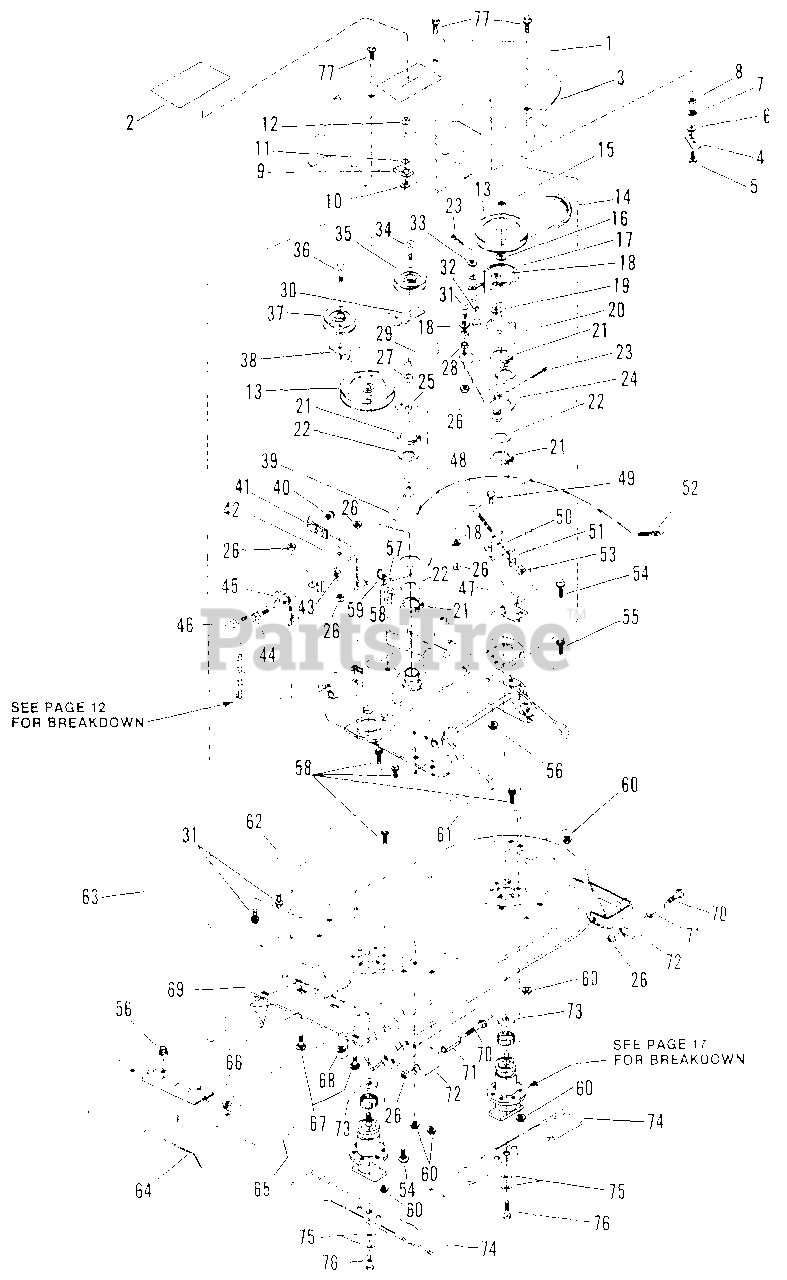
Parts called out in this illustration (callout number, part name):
1	ASSEMBLY, 41" Cover-Top
2	DECAL-CAUTION
3	ASSEMBLY, 41" Cover-Bottom
4	GUIDE, Belt
5	SCREW, 1/4-20 x 1/2" Hex Head Cap
6	WASHER, 1/4 Flat
7	WASHER, 1/4 Internal Tooth Lock
8	NUT, 1/4 Hex
9	CLIP
10	RETAINER, Bolt, 3/8"
11	WASHER, 3/8 Split Lock
12	NUT, 3/8-16 Hex
13	PULLEY, 5" O.D.
15	LOCKNUT, 3/4-16 Hex Jam
16	WASHER, 3/4 Flat
17	BAND, Brake Assembly
18	WASHER, 3/8" Flat
19	SPACER
20	BRAKE DRUM
21	RING, 2" External Retaining
22	WASHER, 2" I.D.
23	COTTER-PIN, 3/32 x 3/4"
24	BRAKE ARM ASSEMBLY
25	ANCHOR. Bl. Cont. Cable
26	LOCKNUT, 3/8-24 Hex
28	SPACER. 3/8 I.D.
30	RESTRICTOR, Belt
31	SCREW, 3/8-24 x 3/4" Hex Hd. Cap
32	PIN, 1/4 Clevis
33	WASHER, 1/4 Flat
34	SCREW, 3/8-24 x 2" Hex Hd. Cap
35	PULLEY, Idler
36	SCREW, 3/8-24 x 1-3/4" Hex Hd. Cap
37	PULLEY. Idler
38	GUIDE, Belt
39	IDLER ARM ASSM'Y.
40	SCREW. 5/16-18 x 5/8" HFST
41	BRACKET, Cable
42	SUPPORT, Idler
43	NUT, 3/8-16 Hex
44	SCREW, 3/8-16 x 1"
45	BRACKET
46	SCREW, 3/8-16 x 3/4" Hex Cap
47	BRACKET, Height Indicator
48	EYE-BOLT
49	BOLT, 5/16-18 x 3/4" SNC
50	ANCHOR
51	T-NUT
52	SPRING, Blade Brake
53	NUT, 1/4-20 Hex
54	BOLT, 3/8-16 x 3/4" SNC
55	BOLT, 3/8-16 x 3/4" HFL
56	NUT, 5/16-18 HFL
57	BRACKET, Deck Interlock
58	SCREW, 1/4-28 x 5/8" HHC
59	NUT, 1/4-28
60	NUT, 3/8-16 HFL
61	DECAL-CAUTION (Rotating Blades)
62	PLATE, Model Number
63	DECAL-CAUTION (Rotating Blades)
64	ASSEMBLY, Side Chute
65	DECAL, Danger (Keep Hands & Feet Away)
66	WINGNUT, 5/16-18
67	BOLT, 5/16-18 x 5/8" SNC
68	RETAINER, Bolt, 5/16
69	ASSEMBLY, Deck
70	SCREW, 3/8-24 x 3-3/4" HHC
71	SPACER
72	ROLLER
74	BLADE, 21"
75	WASHER, Cone
76	SCREW, 3/8-24 x 1-1/4"
77	SCREW, 1/4-28 x 5/8" HHST
